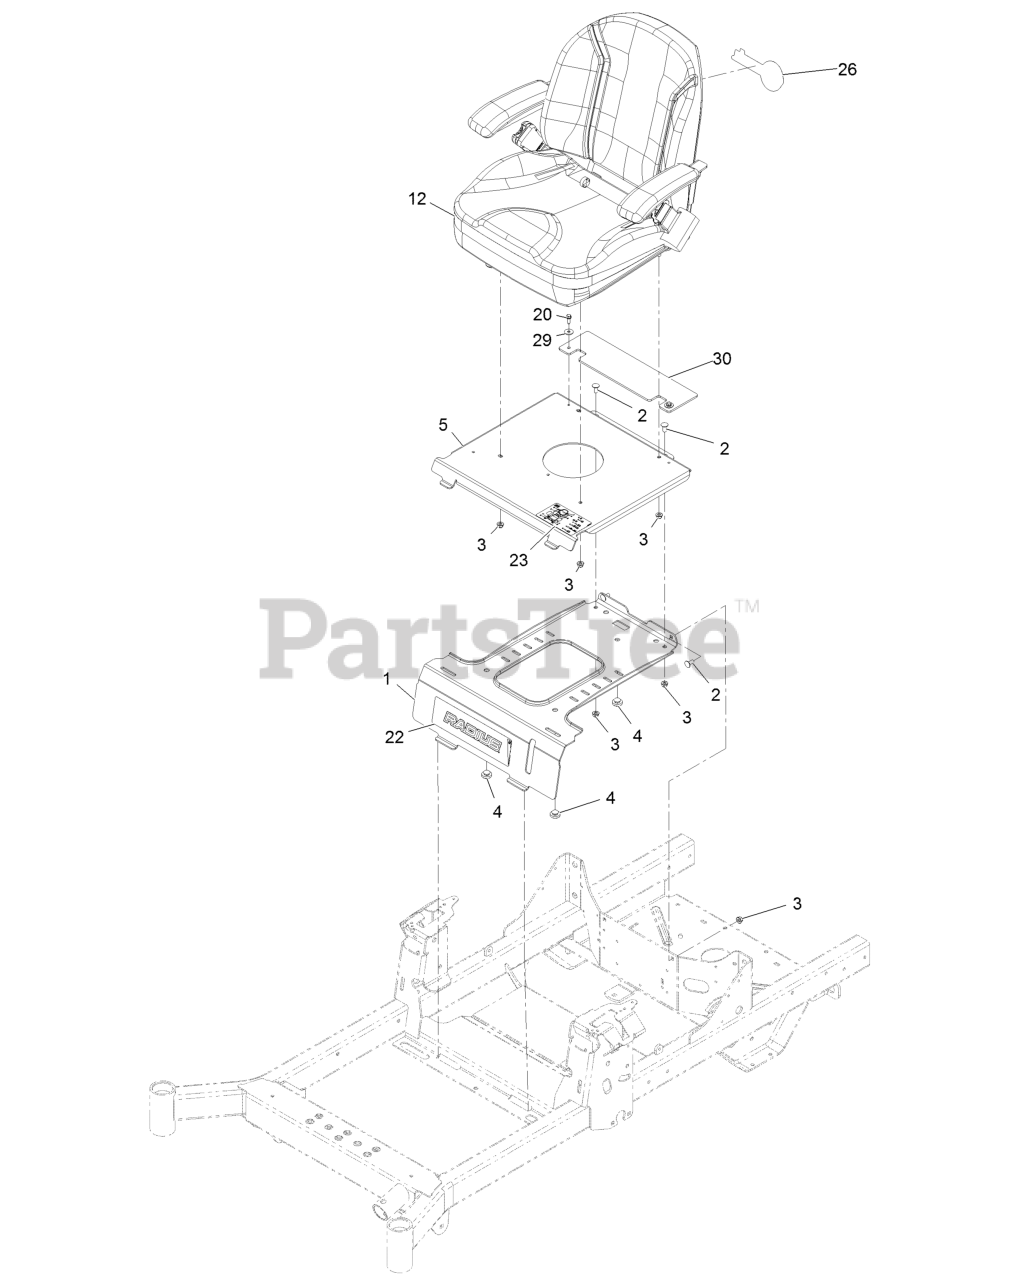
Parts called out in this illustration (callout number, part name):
1	Plate-Retainer, Tank
2	Bolt-Carriage 5/16-18 X 3/4 Short Neck
3	Nut-Nyloc 5/16-18 Flg
4	Bumper-Seat
5	Plate-Seat, Fixed
12	ASM-Seat Exmark
20	Screw-HWH 1/4-20 X 3/4
22	Decal-Radius Logo
23	Decal-Aid, Service
26	Decal-Exmark Logo
30	Guard, Rubber
